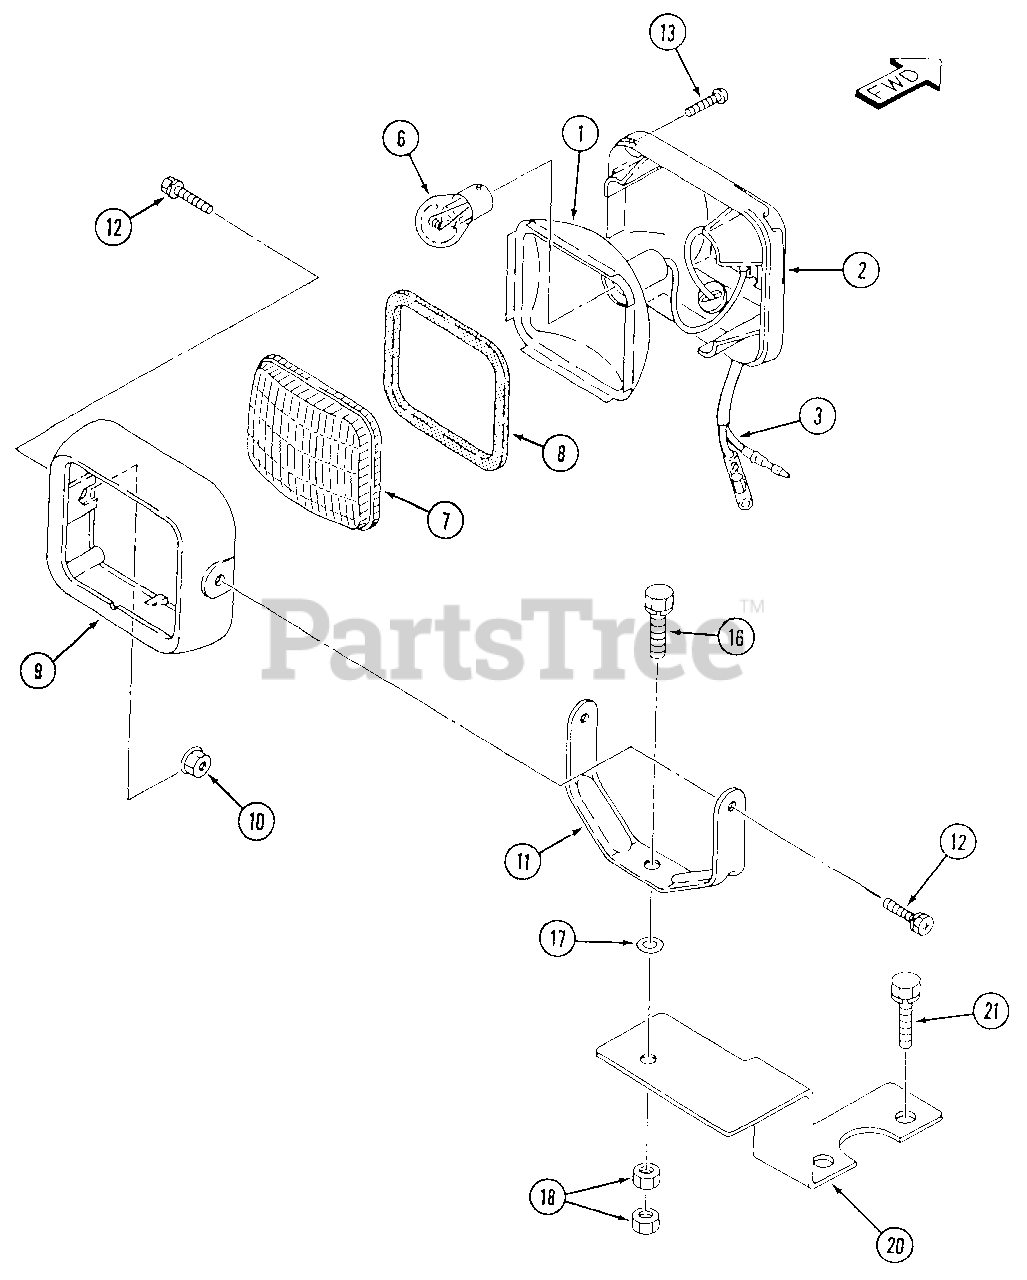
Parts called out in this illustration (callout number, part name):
1	Reflector, Component
2	Housing, Component
3	Lead, Component
9	Rim
13	Screw, Tapping
